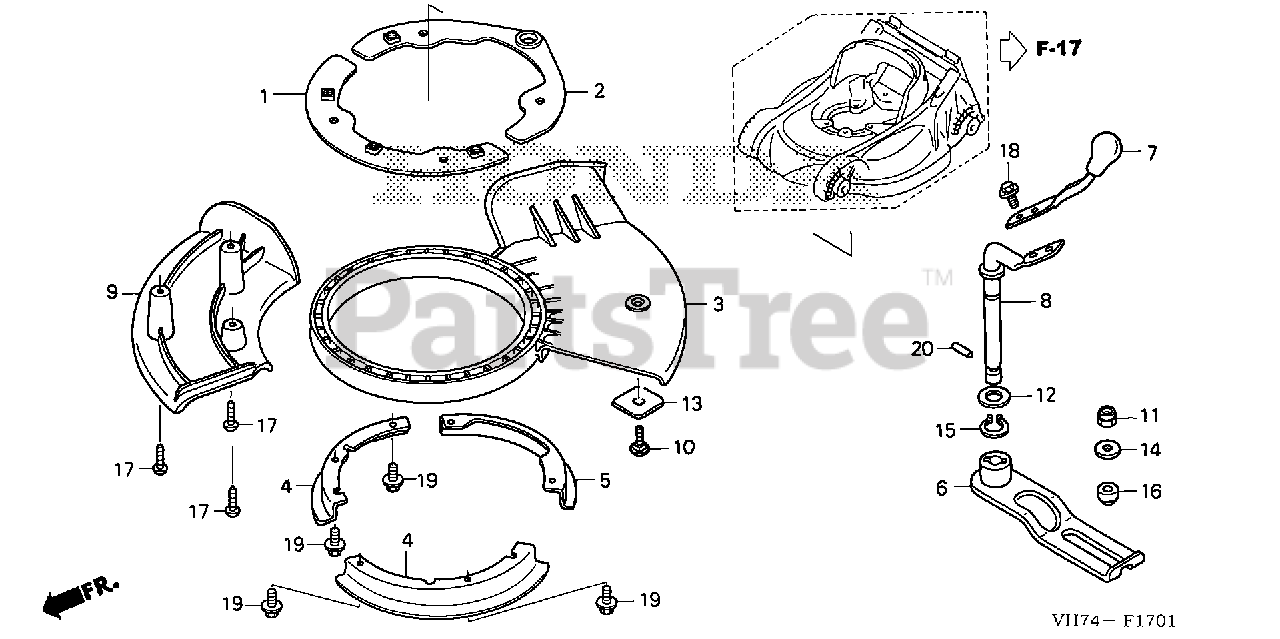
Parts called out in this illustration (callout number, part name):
1	PLATE, FR. BASE
2	PLATE, RR. BASE
3	SHUTTER
4	HOLDER, FR. SHUTTER
5	HOLDER, RR. SHUTTER
6	ARM, SHUTTER
7	LEVER, SHUTTER *G186R* (GRANNY APPLE GREEN)
8	ARM, LEVER
9	RAMP, SCROLL
10	BOLT, SPECIAL (6X19)
11	NUT, NYLON LOCK (6MM)
12	WASHER, THRUST (13MM)
13	WASHER, ARM
14	WASHER (6.5X18)
15	CIRCLIP (OUTER) (12.7MM)
16	COLLAR, ARM
17	SCREW, TAPPING (5X16)
18	BOLT, FLANGE (6X8)
19	BOLT, FLANGE (8X10)
20	ROLLER (4X19.8)
